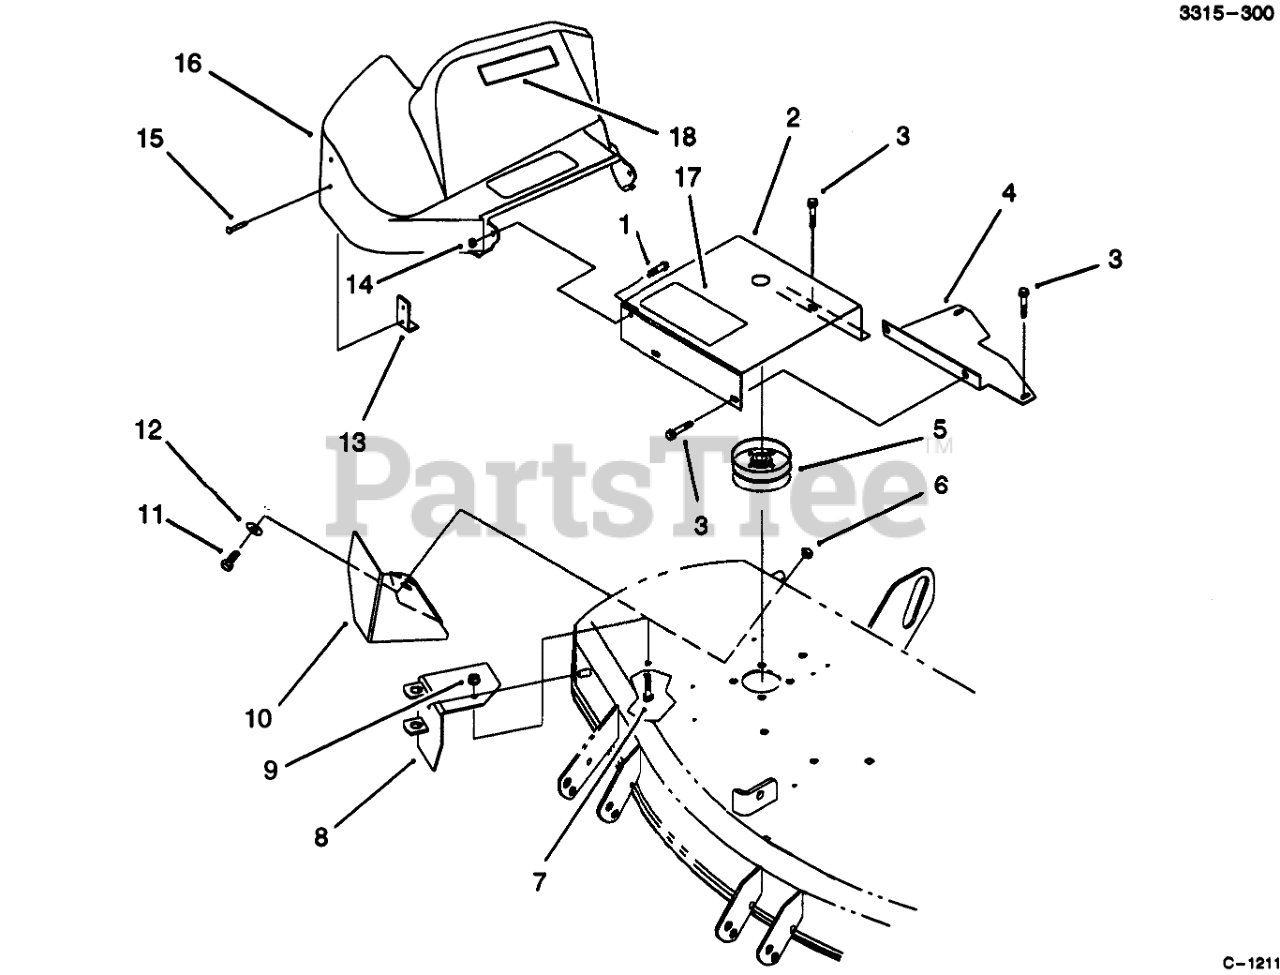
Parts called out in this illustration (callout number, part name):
1	SCREW-HH
2	Inner Shield Assembly (Incl. Ref. #17)
3	Bolt
4	42" ADAPTOR SHIELD B
5	PULLEY
6	NUT-LOCK, NI
7	SCREW-HH
8	PIVOT SUPPORT ASM
9	NUT-HF
10	42" DEFLECTOR B
11	SCREW-HH
12	WASHER-FLAT
13	BRACKET-SUPPORT, SHIELD
14	NUT-LOCK, NI
15	RIVET-POP
16	SHIELD-BELT
17	DECAL-DANGER, THROWN OBJECT
18	DECAL - DANGER
